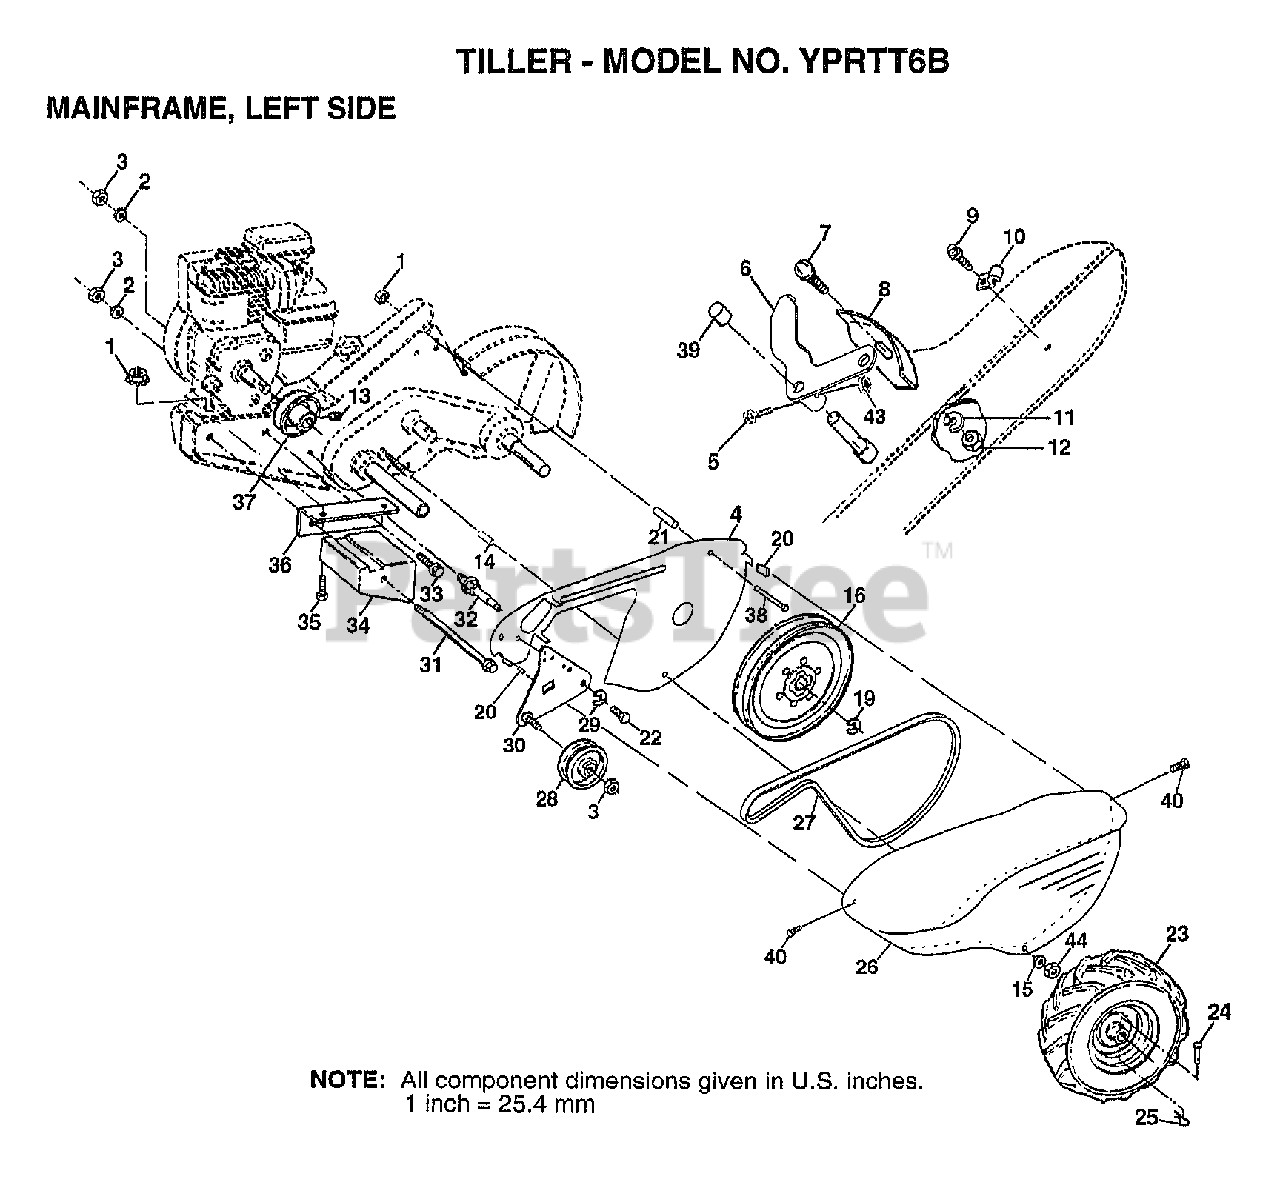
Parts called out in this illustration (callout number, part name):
2	LOCKWASHER
3	NUT.HEX.3/8-16UNC
4	SHIELD.INNER.BELT
5	"SCREW-LEVER,SHI"
6	LEVER ASM CRT
7	BOLT
8	PANEL TI
10	CONDIUT CLIP T
11	LOCKWASHER
13	SET SCREW
14	SPACER-SPLIT
15	WASHER
16	SHEAVE.TRANS.
20	NUT J CLIP #8
21	SPACER CRT
22	BOLT.FIN.HX.5/16-24X1/2
23	TIRE TI
23	RIM
24	RIVET.DRILL.1.75
25	RETAINER M
26	GUARD.BELT
27	BELT-V
28	PULLEY-IDLER TI
29	KLIP RING
30	BRACKET ASM IDLER
31	BOLT CRT
32	SHIFT ARM CRT
33	BOLT
34	COUNTERWEIGHT CRT
35	BOLT
36	BRACKET LH CRT
37	ENGINE PULLEY
39	CAP PLUNGER BLACK
40	SCREW HX WSH.HD#8-18X1/2
43	LOCKNUT
44	NUT
